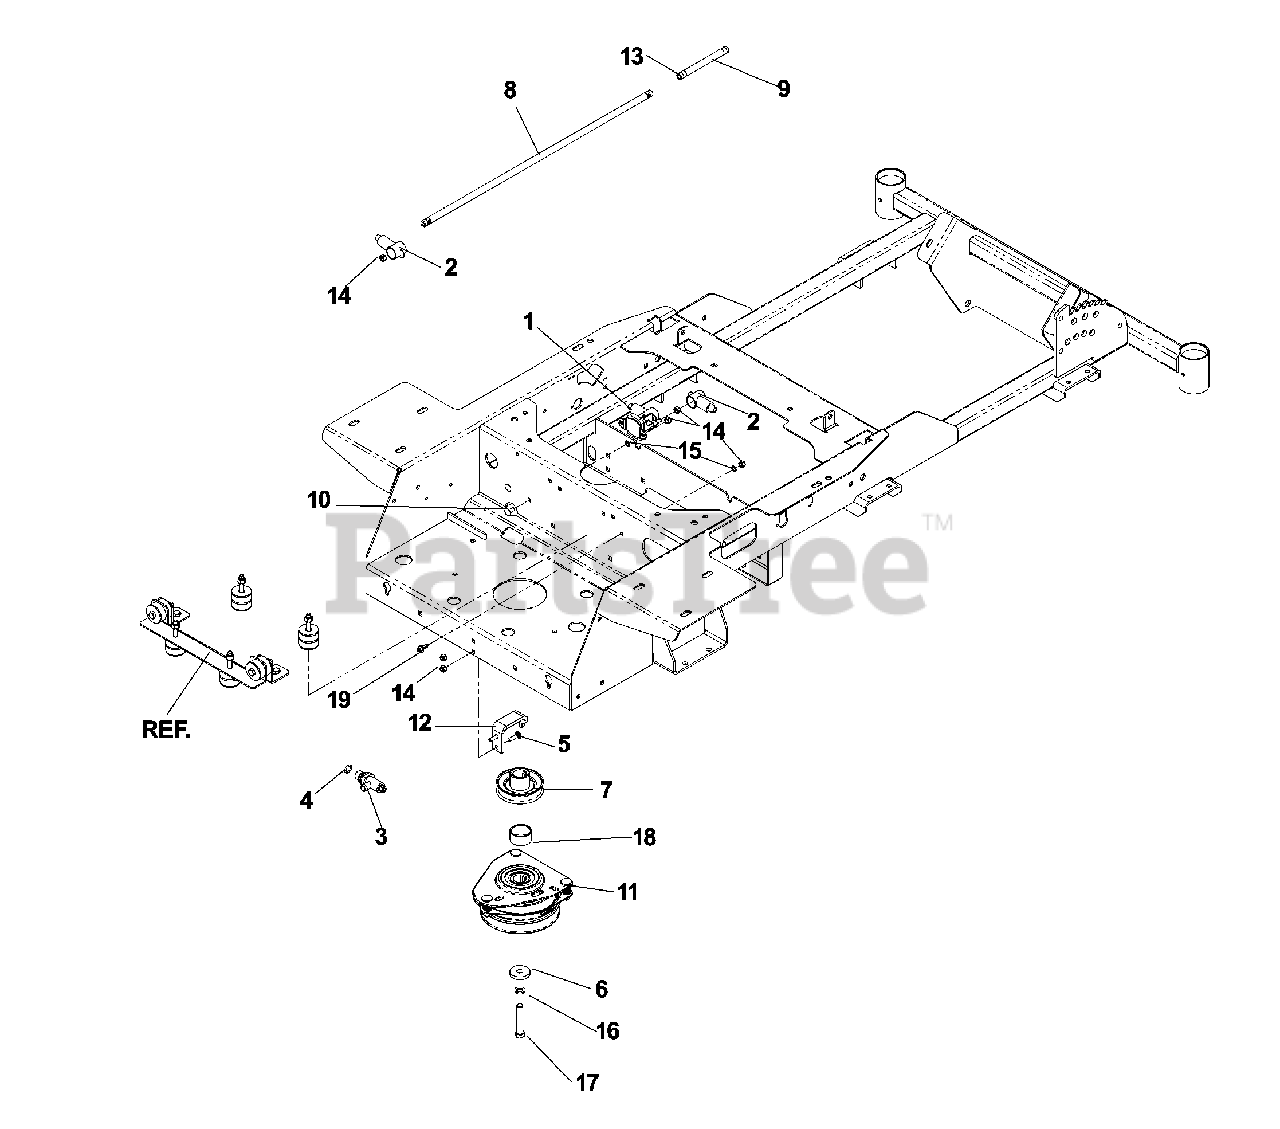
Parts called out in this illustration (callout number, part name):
1	SOLENOID
2	INSULATOR
3	VALVE ASSEMBLY
5	RHSNB, 1/4-20 X 1, GR5
6	CLUTCH, WASHER
7	PULLEY, ENGINE
8	FUEL LINE 24"
9	FUEL LINE 5"
10	RHSSNB, 1/4-20X5/8
11	CLUTCH, OGURA - 90 FT/LB
12	TIE DOWN, CLUTCH
13	HOSE CLAMP
14	NUT 1/4-20 NYLOC
15	WASHER 1/4 INT TOOTH
16	WASHER 7/16 LOCK
17	HEX SCREW 7/16-20 X 3
18	SPACER, ENGINE - PULLEY
19	SCREW- 1/4-20 X 5/8
